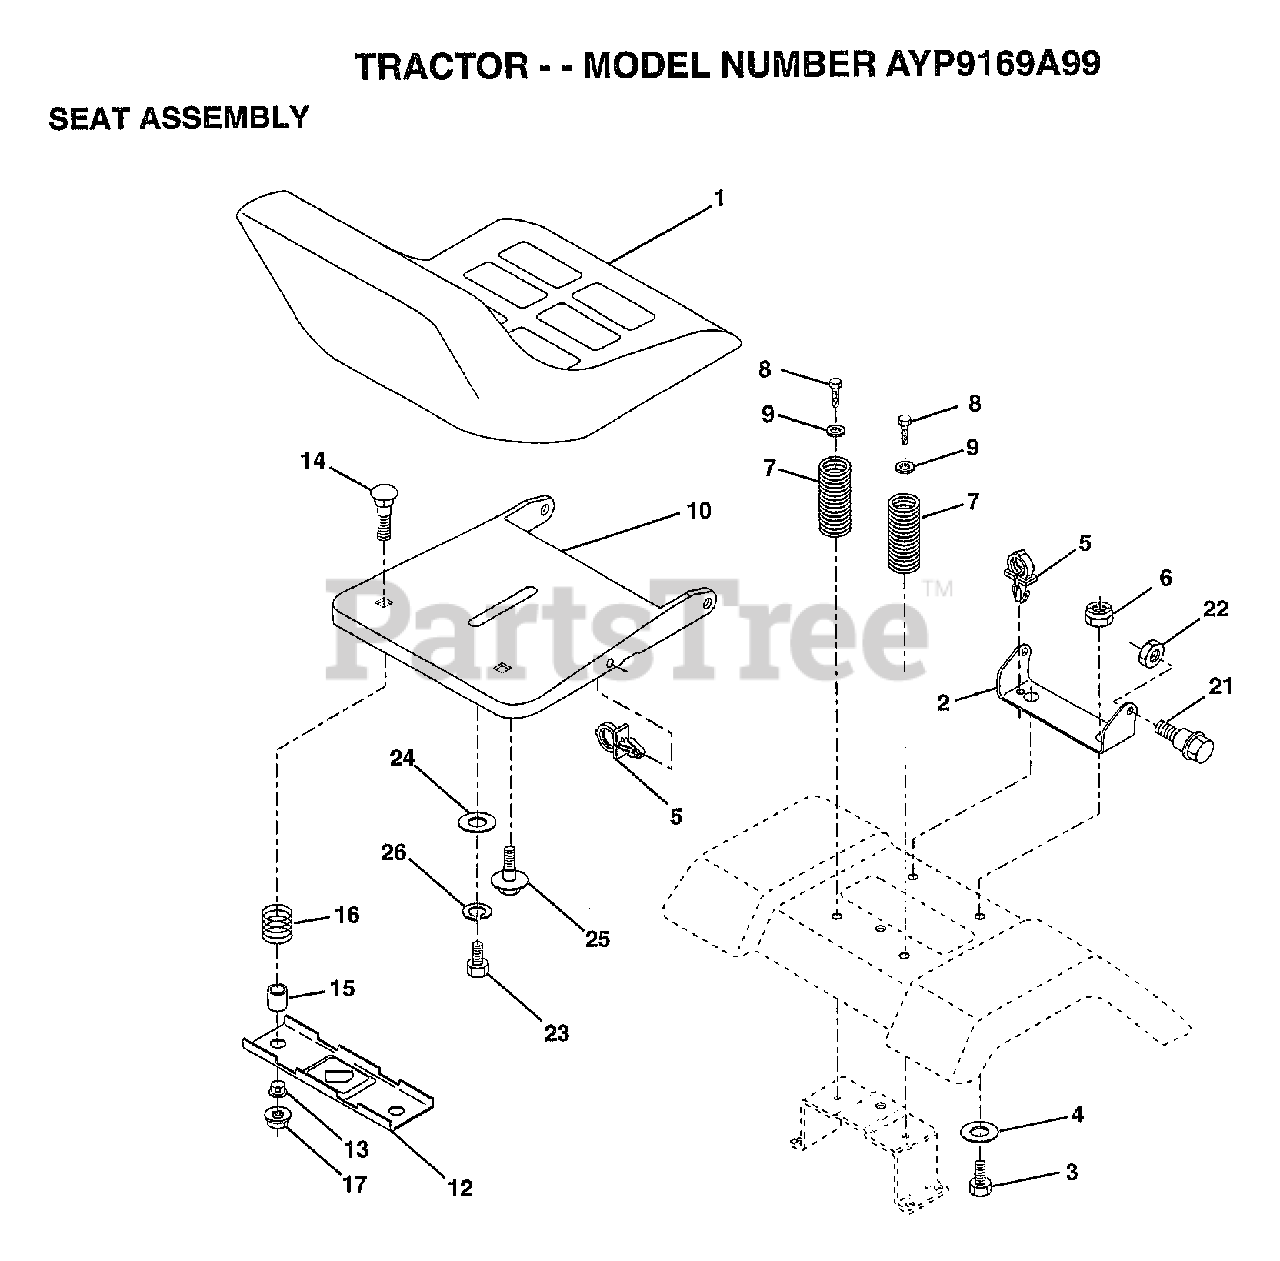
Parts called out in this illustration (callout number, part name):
2	BRACKET PVT SEAT
3	BOLT
4	WASHER PM
5	CLIP.PUSH-IN.HING
6	NUT
7	SPRING COMPRESSIO
8	SCREW GTV
9	WASHER
10	PAN-SEAT
12	BRKT SWITCH
13	BUSHING
14	BOLT-RD HD SQ NK
15	SPLIT SPACER
16	SPRING
21	"BOLT,SHOULDER"
22	NUT
23	BOLT
24	WASHER
25	"BOLT,SHOULDER"
26	LOCKWASHER
